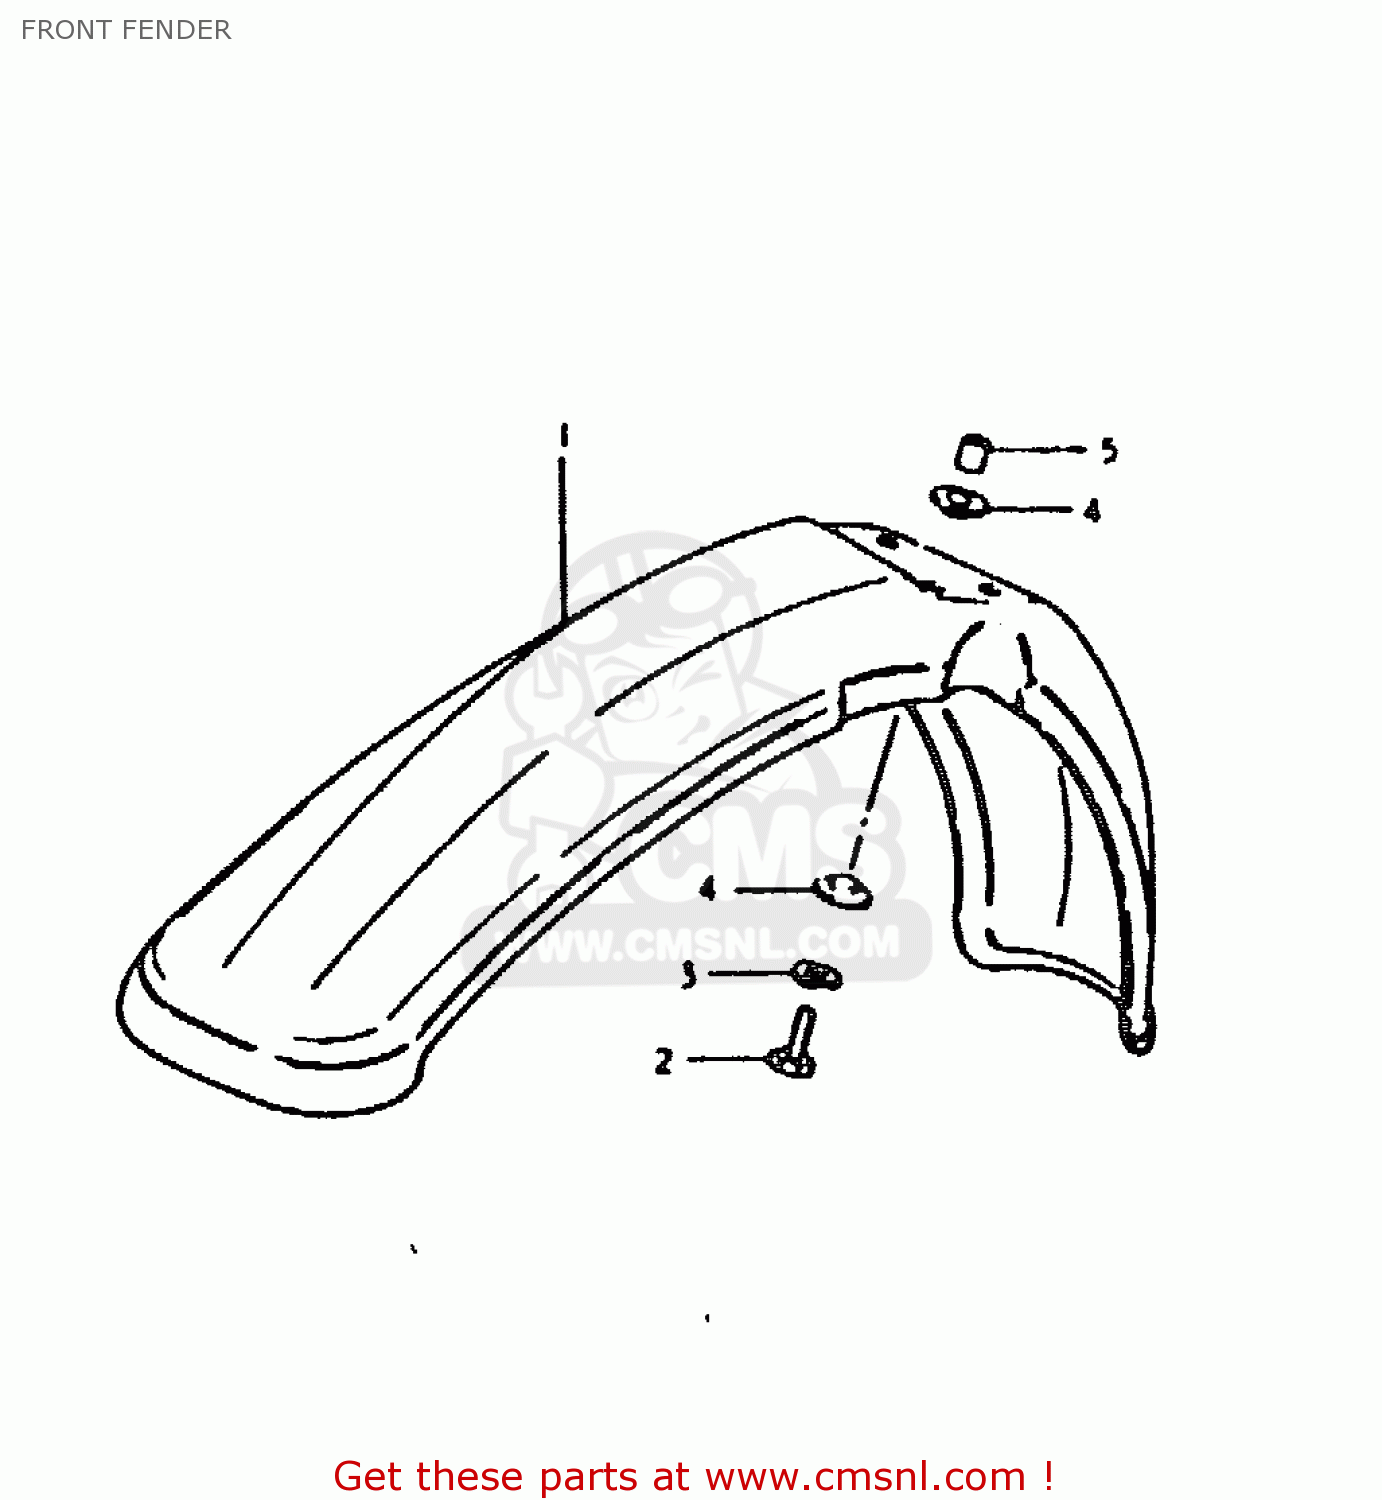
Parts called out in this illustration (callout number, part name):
1	FENDER,FR
2	BOLT
3	LOCK WASHER
4	SPACER
5	SPACER
